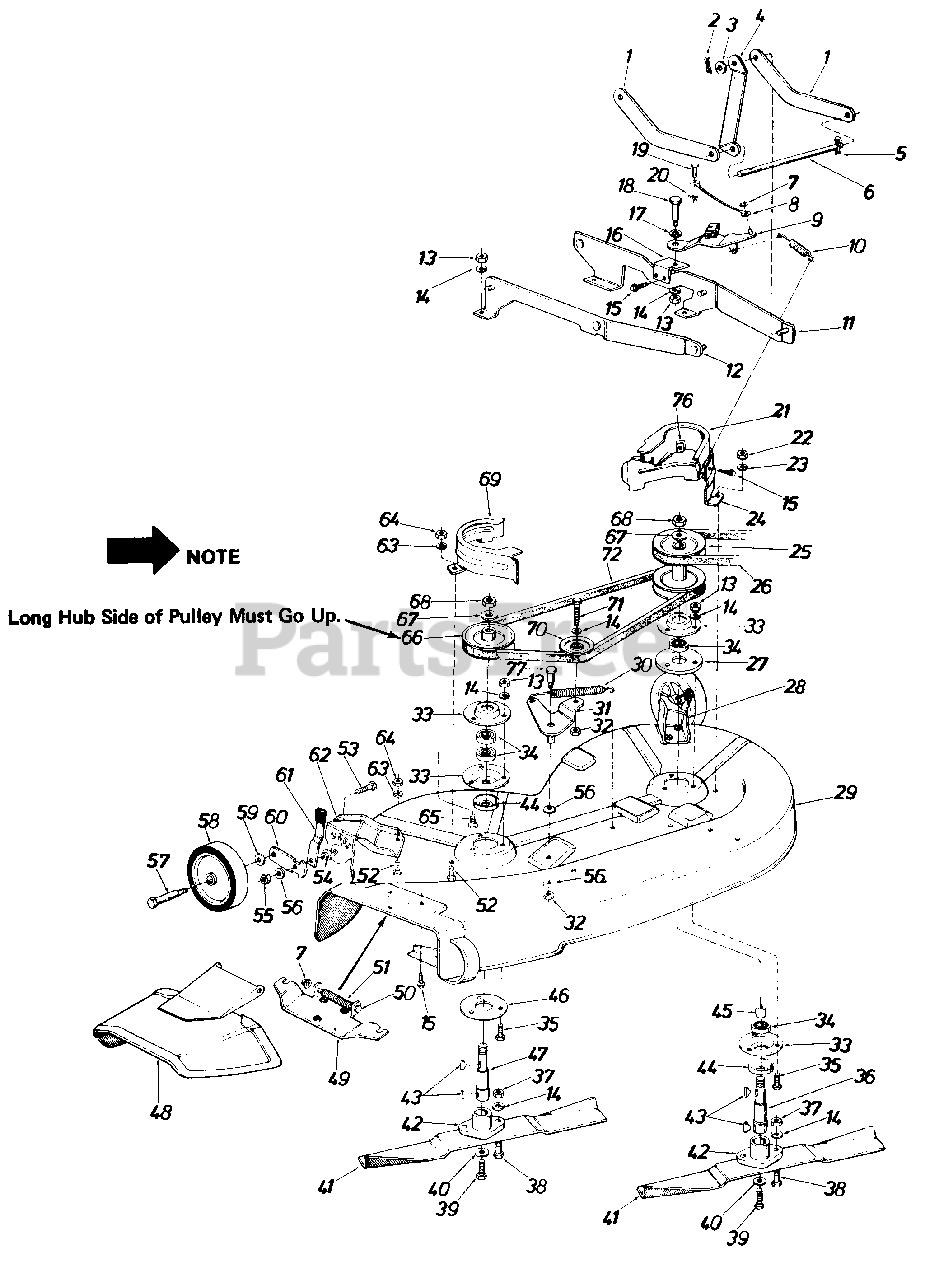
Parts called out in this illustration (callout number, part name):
3	Fl-Wash. 50" I.D. x 1.00" O.D. x .090 Thk.
6	Deck Connecting Rod
7	Push Cap 1/4" Rod
8	Brake Cable Ass'y.
9	Spi nd le Brake Arm Ass'y.
10	Extension Spring
11	Hanger Brkt. Ass'y.-L.H. Side
12	Hanger Brkt. Ass'y. R.H. Side
13	Hex Nut 5/16-18 Thd.
14	L-Wash. 5/16" I.D.
15	Hex Wash. Hd. Self-Tap Scr. 1/4-20 x .50" Lg.
16	Spindle Brake Pivot Brkt.
17	Wave Wash..438" I.D. x . 750" O. D. x .15 Thk.
18	Shld. Bolt.437" Dia. x .162" Lg. 5/16-18 Thd.
19	Clevis Pin 1/4" Dia. x 1.00" Lg.
20	Hairpin Cotter 1/4" Dia.
21	Upper Belt Guard L.H. Side
22	Hex Nut 1/4-20 Thd.
23	L-Wash. 1/4" I.D.
24	Lower Belt Guard L.H. Side
25	Deck Drive Pulley
26	"V"-Belt 1/2" x 51.0" Lg. (Kevlar) "A" Sec.
27	Spindle Spacer Plate
28	Wheel Brkt. L.H. Side
29	38" Deck Ass'y.
30	Extension Spring
31	Deck Idler Brkt. Ass'y.
32	Hex Cent. L-Nut 3/8-16 Thd.
33	Bearing Housing
34	Ball Brg. .787 I.D. x 1.85 O.D x .55
35	Hex Bolt 5/16-18 x 1.0" Lg.
36	Blade Spindle
37	Hex Nut 5/16-24 Thd.
38	Hex Bolt 5/16-24 x 1.00" Lg. *
39	Hex Bolt3/8-24 x 1.50" Lg.
40	L-Wash. 3/8" I.D. Heavy Duty
41	19" Blade
42	Blade Adpater Kit
43	#6 Hi-Pro Key 5/32 x 5/8" Dia.
44	Bearing Shield
45	Spacer.790" I.D. x 1.0" O.D. x.315 Lg.
46	Deck Reinforcement Plate
47	Blade Spindle
48	Chute Cover Ass'y.
49	Adapter Plate
50	Hinge Pin
51	Torsion Spring
52	Hex Bolt 1/4-20 x .50" Lg.
53	Hex Bolt3/8-16 x 1.25" Lg.
54	Shoulder Spacer
55	HexJam L-Nut3/8-16Thd.
56	BellevilleWash. .400" I.D. x 1.13" O.D. x .030
57	Shld. Bolt. 498 Dia. x 1.53" Lg.
58	Deck Wheel 5" Plastic Comp.
59	Belleville Wash. .400" I.D. x .88" O.D. x .060
60	Wheel Pivot Bar Deck
61	Spring Lever Ass'y. w/Knob
62	Wheel Brkt. R.H.
63	L-Wash. 1/4" I.D.
64	Hex Nut 1/4-20 Thd.
65	Sems Truss Hd. Scr. 5/16-18 x.50" Lg.
66	Pulley 4.75" O.D.
67	L-Wash. 5/8" I.D.
68	Hex Jam Nut 5/8-18 Thd.
69	Belt Guard
70	4" "V"-Idler Pulley
71	Hex Bolt 3/8-16 x 1.25" Lg.
72	"V"-Belt.50" x 53.0 Lg. (4L)
76	Speed Nut 1/4-20 Thd.
77	Shld. Bolt .50" Dia. x .71" Lg. 3/8-16 Thd.
